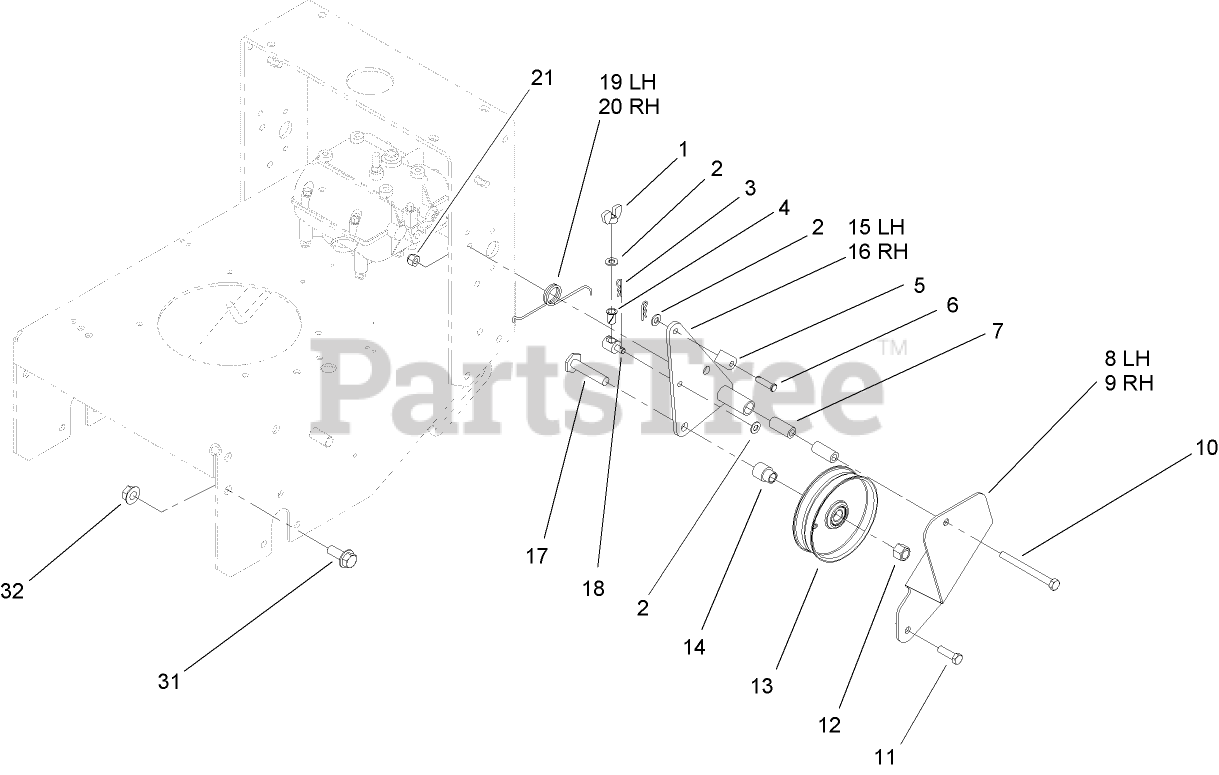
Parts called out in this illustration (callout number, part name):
1	NUT-WING
2	WASHER-PLAIN
3	PIN-COTTER
4	BUSHING-NYLON
5	FITTING-ROD
6	PIN-CLEVIS
7	SPACER-PIVOT, IDLER
8	SUPPORT-IDLER, LH
9	SUPPORT-IDLER, RH
10	SCREW-HH
11	SCREW-HH
12	NUT-LOCK, NI
13	PULLEY-IDLER
14	SPACER-PULLEY
15	ARM-IDLER, LH
16	ARM-IDLER, RH
17	SCREW-LEVELER
18	FITTING-ROD
19	SPRING-TORSION, LH
20	SPRING-TORSION, RH
21	NUT-LOCK, NI
31	SCREW-HHF
32	NUT-HF
